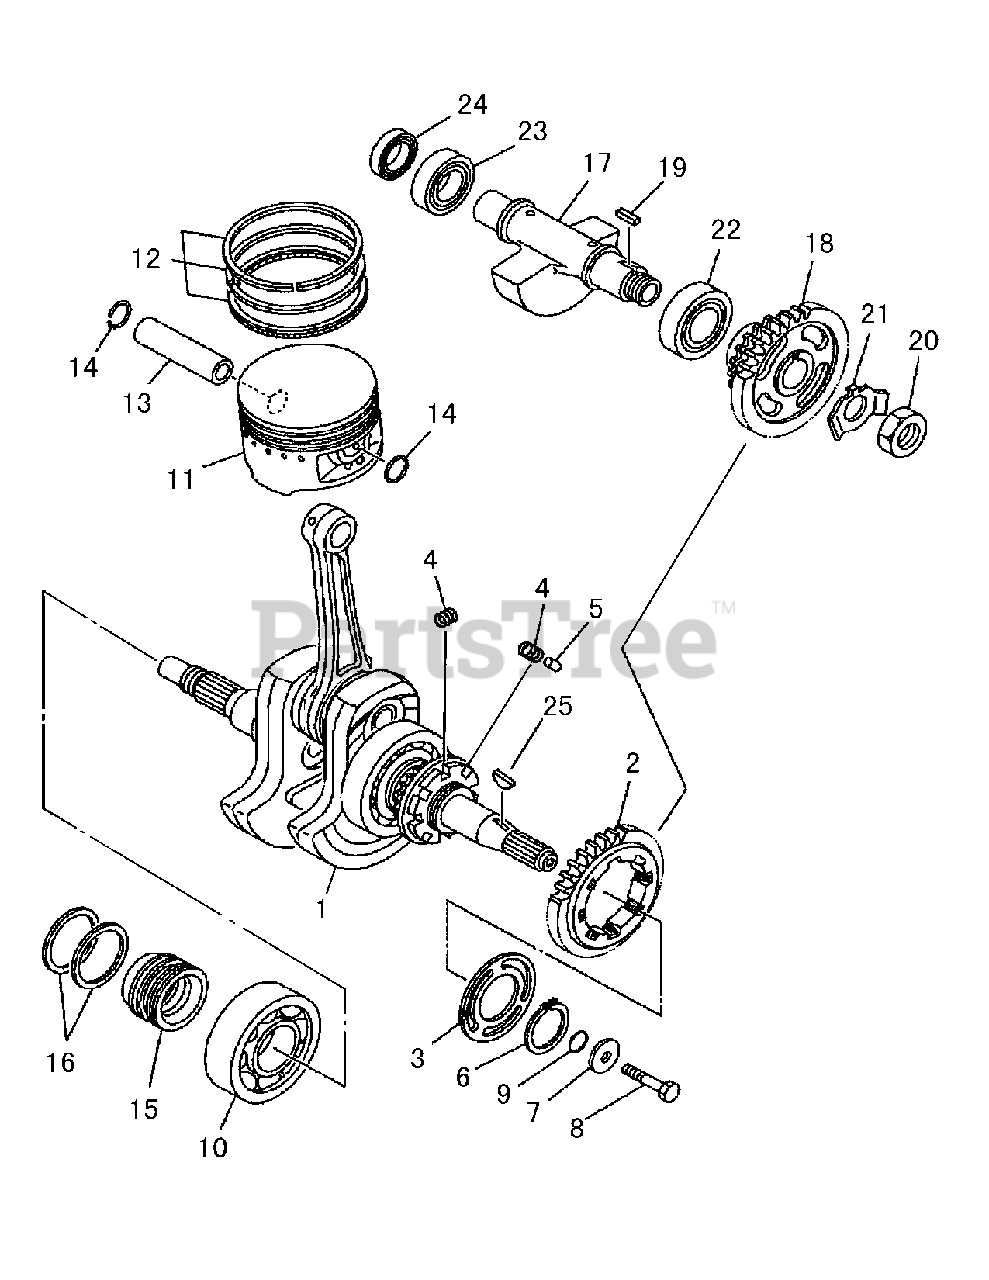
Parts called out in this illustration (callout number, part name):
1	Connecting Rod-Complete
2	Gear-Balanced Initiative
3	Clamper Plate-Initiative
4	Spring-Buffer
8	Hexagon Head Bolt
11	Piston
12	Piston Ring-Complete
13	Pin-Piston
14	Circlip:Piston Pin
15	Seal-Ring Sheath
17	Shaft Asm-Balanced
18	Driven Gear-Balanced
21	Thrust Washer
25	Key-Semi Circle
